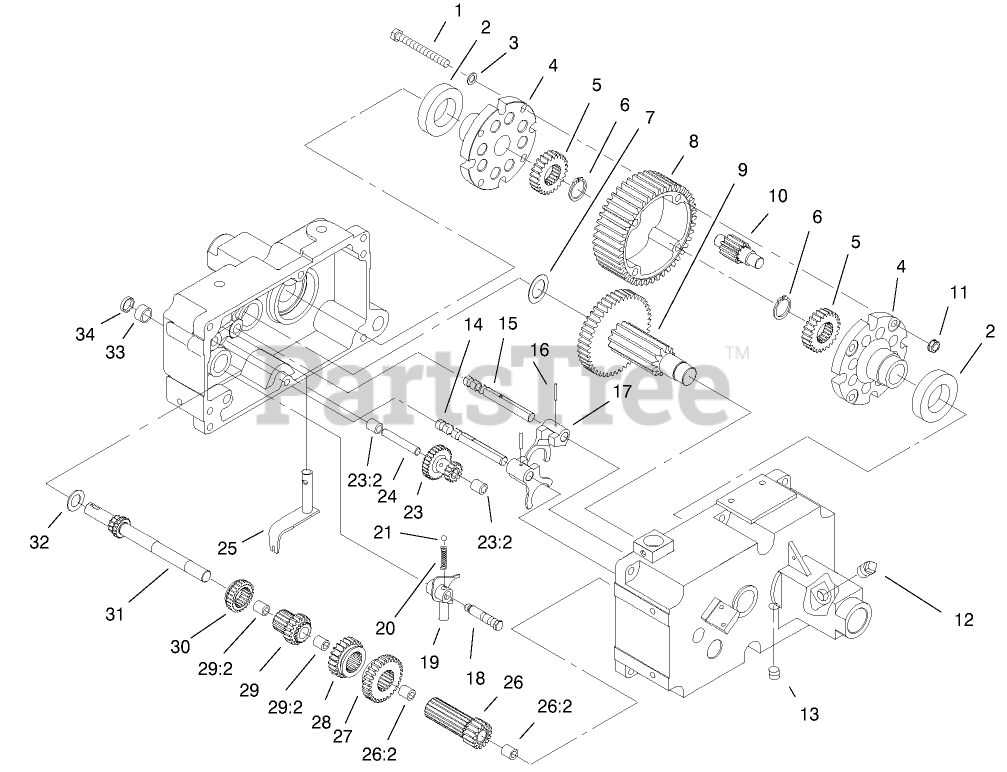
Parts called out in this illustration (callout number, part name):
2	BEARING-BALL
3	WASHER
4	END CAP-DIFFERENTIAL
5	GEAR-AXLE DIFFERENTIAL
6	RING-SNAP
7	WASHER-THRUST
8	GEAR-DIFFERENTIAL RING, 43T
9	GEAR ASM
10	GEAR-PINION, 11T
11	NUT-HEX
12	PLUG-PIPE, SQH
13	PLUG-PIPE
14	RAIL-SHIFT
15	RAIL-REAR SHIFT
16	PIN-ROLL
17	FORK-SHIFT
18	BOLT-DETENT
20	SPRING-SHIFT STOP
21	BALL-DETENT
23	ASM-GEAR REDUCTION
23:2	BEARING-NEEDLE
24	GEAR-SHAFT REDUCTION
25	SHIFT ASM
26	GEAR
26:2	BEARING-NEEDLE
27	GEAR-LOW AND REVERSE
28	GEAR-HI AND 2ND
29	GEAR
29:2	BEARING-NEEDLE
30	GEAR-SLIDING
31	SHAFT-INPUT
32	WASHER-THRUST
33	BEARING-NEEDLE
34	SEAL-OIL
